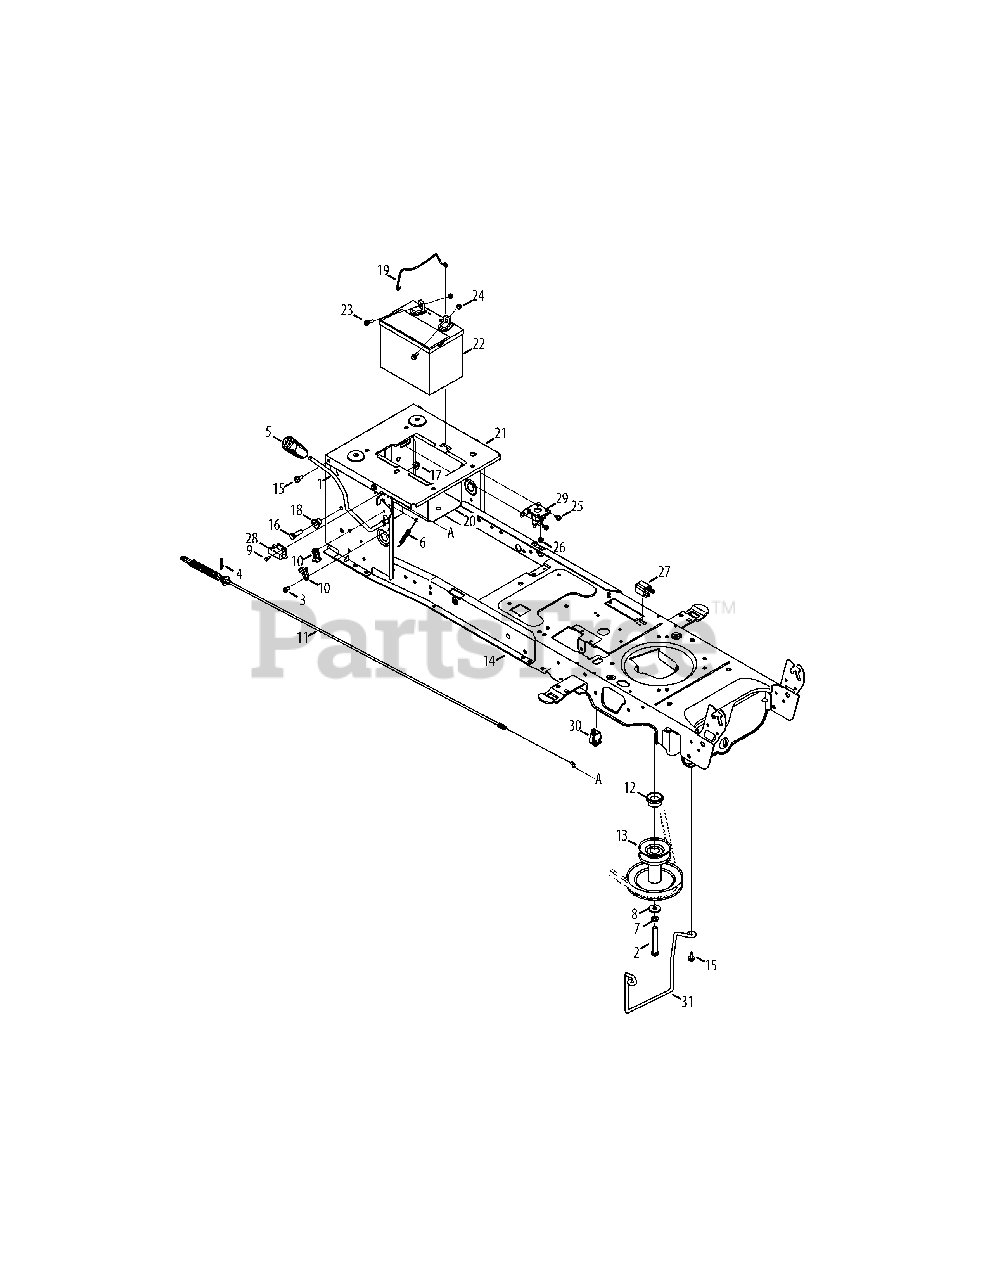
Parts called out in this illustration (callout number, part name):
1	Handle Ass’y, PTO
2	Hex Screw, 7/16-20, 3.50, Gr5
3	Screw, Self-tapping, 1/4-20, 0.50
4	Pin, Cotter, Bow-Tie 72
5	Grip, Handle, 3/8
6	Spring, Ext, .38 Dia x 5.6
7	Washer, Lock, 7/16, Regular Duty
8	Washer, Flat, .450 x 1.250 x .164
9	Screw, Shoulder, #10-32, .500
10	Bearing, PTO
11	Cable, Engag, Deck
12	Spacer, 1.010 x 1.400 x .825
13	Pulley, Engine, 3.56 x 6.12 Dia.
14	Frame Ass’y, Lower
15	Screw, Self-tapping, 5/16-18, .750,
16	Hex Screw, 3/8-16, 1.25, Gr5, Std
17	Nut, Flange Lock, 3/8-16, Grf,
18	Spacer, Shoulder, .38 x 1.0 x .70
19	Rod, Battery
20	Tray, Battery
21	Bracket, Frame, Seat
22	Battery
23	Hex Flange Screw, 1/4-20, .75, Gr5
24	Nut, Sems, 1/4-20
25	Screw, Self-tapping, 1/4-20, 0.375
26	Nut, Flange Lock, 1/4-20, Grf,
27	Switch, 3-Pole
28	Switch, Interlock
29	Solenoid, 12V
30	Switch, Plunger, Snap Mount
31	Belt Keeper Rod
